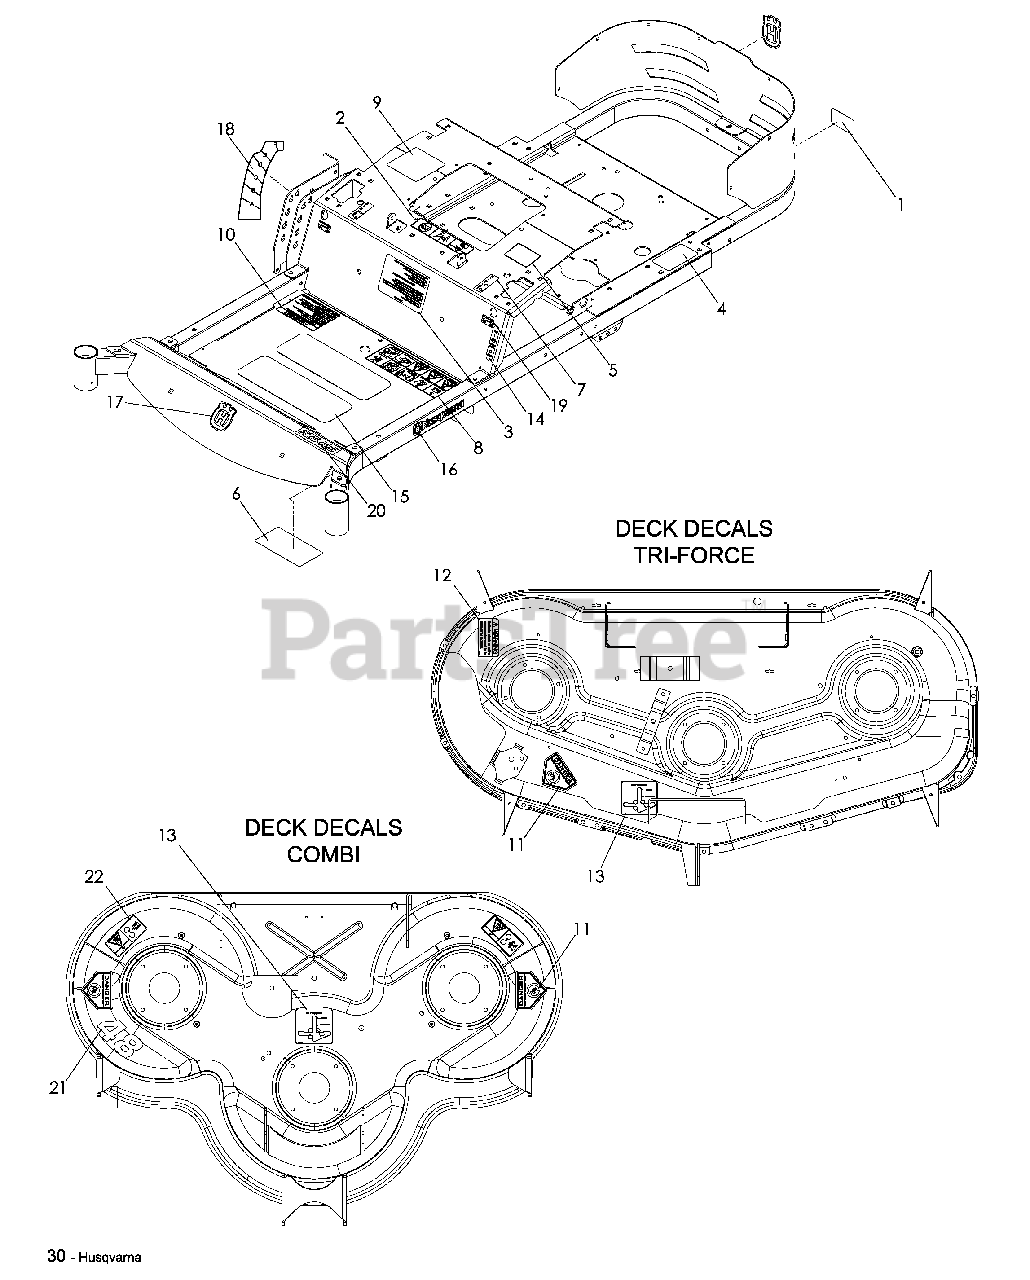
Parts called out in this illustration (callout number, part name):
1	DECAL, PROP 65
2	DECAL, BATTERY WARNING
3	DECAL, START
4	DECAL, DO NOT TOW
5	DECAL, EXIT MOWER
6	DECAL, SERVICE
7	DECAL, MOTION CONTROL
8	DECAL, SAFETY WARN
9	DECAL, RESPONSIBILITY
10	DECAL, WARNING
11	DECAL, DANGER
12	DECAL, WARNING
13	DECAL, BELT ROUTING
14	DECAL, PARK BRAKE
15	ABRASIVE PAD
16	DECAL, HUSQVARNA
17	DECAL, CROWN H
18	DECAL, HEIGHT
19	DECAL, TRACKING
20	DECAL, EZ4824
21	DECAL, 48"
22	DECAL, BELT DRIVES
